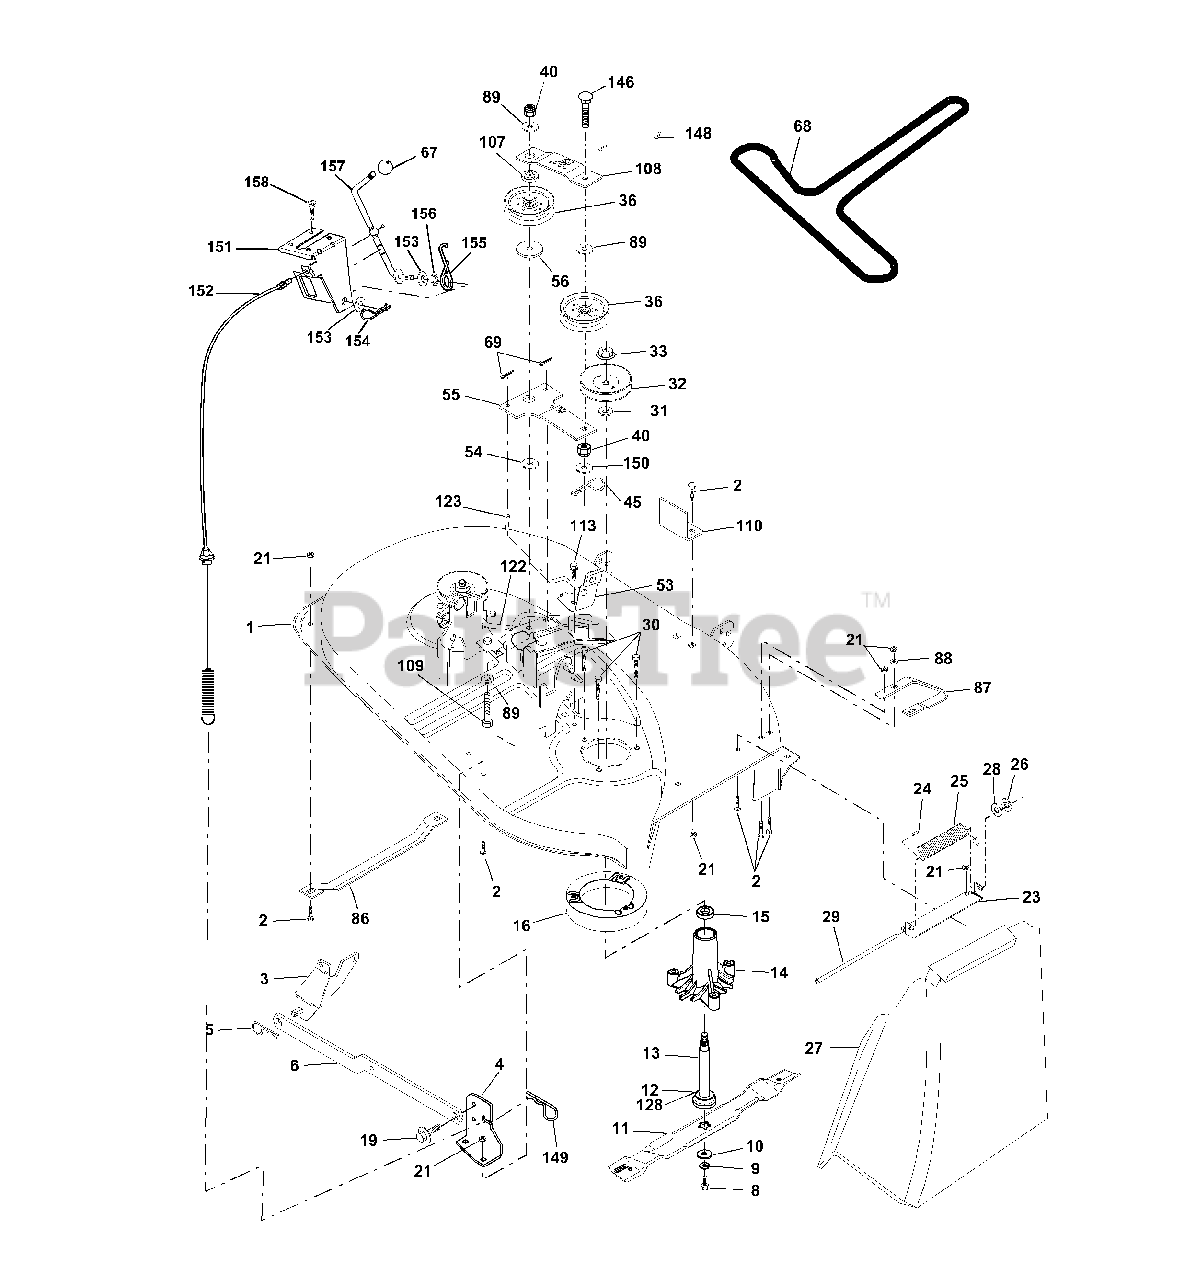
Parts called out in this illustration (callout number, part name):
1	Mower Housing Assembly
2	Bolt Carriage 5/16-18 x 3/4
3	Bracket Asm Fr. Sway Bar
4	Bracket Deck Sway Bar 38"/42"
5	Retainer Spring
6	Arm, Suspension, Rear
8	Bolt 3/8-24 x 1.25 Grade 8
9	Washer, Lock 3/8
10	Washer,Hardened
11	Blade Mower
12	Bearing, Ball
13	Shaft Assembly, Mandrel, Vented
14	Housing, Mandrel, Vented
15	Bearing, Ball, Mandrel
16	Stripper, Vented Mower Deck
19	Bolt, Shoulder
21	Nut
23	Bracket, Mower Deflector
24	Cap, Sleeve
25	Spring, Torsion, Deflector
26	Nut, Push
27	Shield, Deflector
28	Washer 11/32 x 5/8 x 16 Gauge
29	Rod, Hinge
30	Screw Thdrol. Washer Head
31	Washer, Spacer
32	Pulley, Mandrel
33	Nut, Toplock 9/16
36	Pulley, Idler, Flat
45	Retainer
53	Brake Assembly
54	Washer,Hardened
55	Idler Arm Assembly
56	Spacer, Retainer
67	Knob
68	V-Belt, 42" Mower
69	Pin, Cotter 3/32 x 3/4
86	Runner,LH
87	Runner,RH
88	Washer 11/32 x 3/4 x 16 Ga
89	Washer 13/32 x 1 x 12 Ga.
107	Spacer Retainer
108	Stiffener, Idler Arm
109	Bolt, Hex Hd 3/8-16 x 2-1/2
110	Upstop Deck Front 38"
113	Screw 5/16-1/ x 3/4
122	Rod, Brake LH
123	Rod, Brake RH
128	Washer Felt
146	Bolt Carriage Idler
148	Spring Return Idler
149	Retainer Spring Yellow
150	Washer 9/32 x 3/4 x 16 Ga.
151	Bracket Clutch Cable
152	Clutch Cable 38"/46"
153	Washer Flat 3/8" Type B
154	Spring Retainer
155	Spring Retention LVR CLTCH CAB
156	Spacer Clutch Cable
157	Rod Clutch Cable 3/8"
158	Screw Hex Thd Cut 1/4-20 x 5/8
